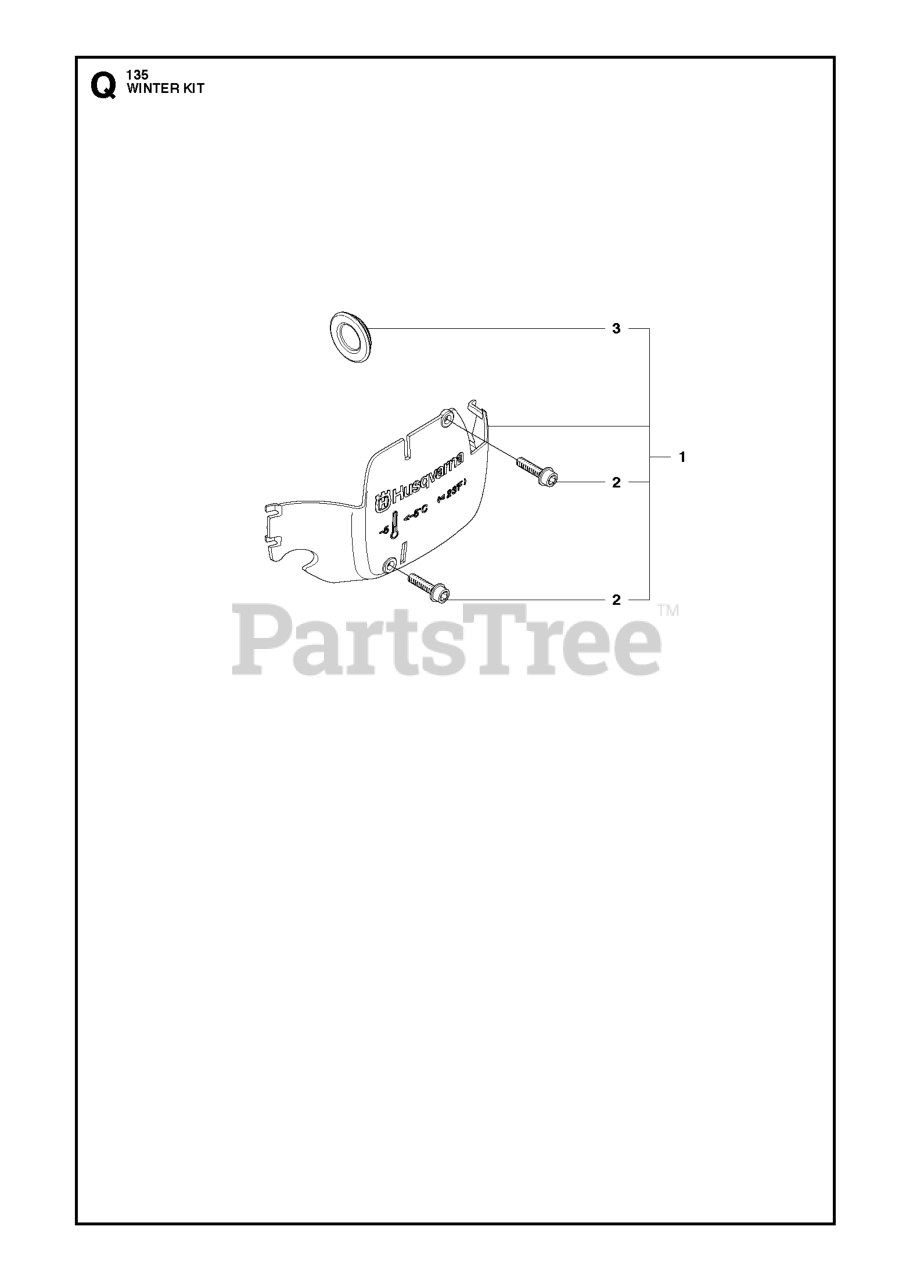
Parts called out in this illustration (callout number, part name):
1	WINTER KIT
2	SCREW
3	PLUG
